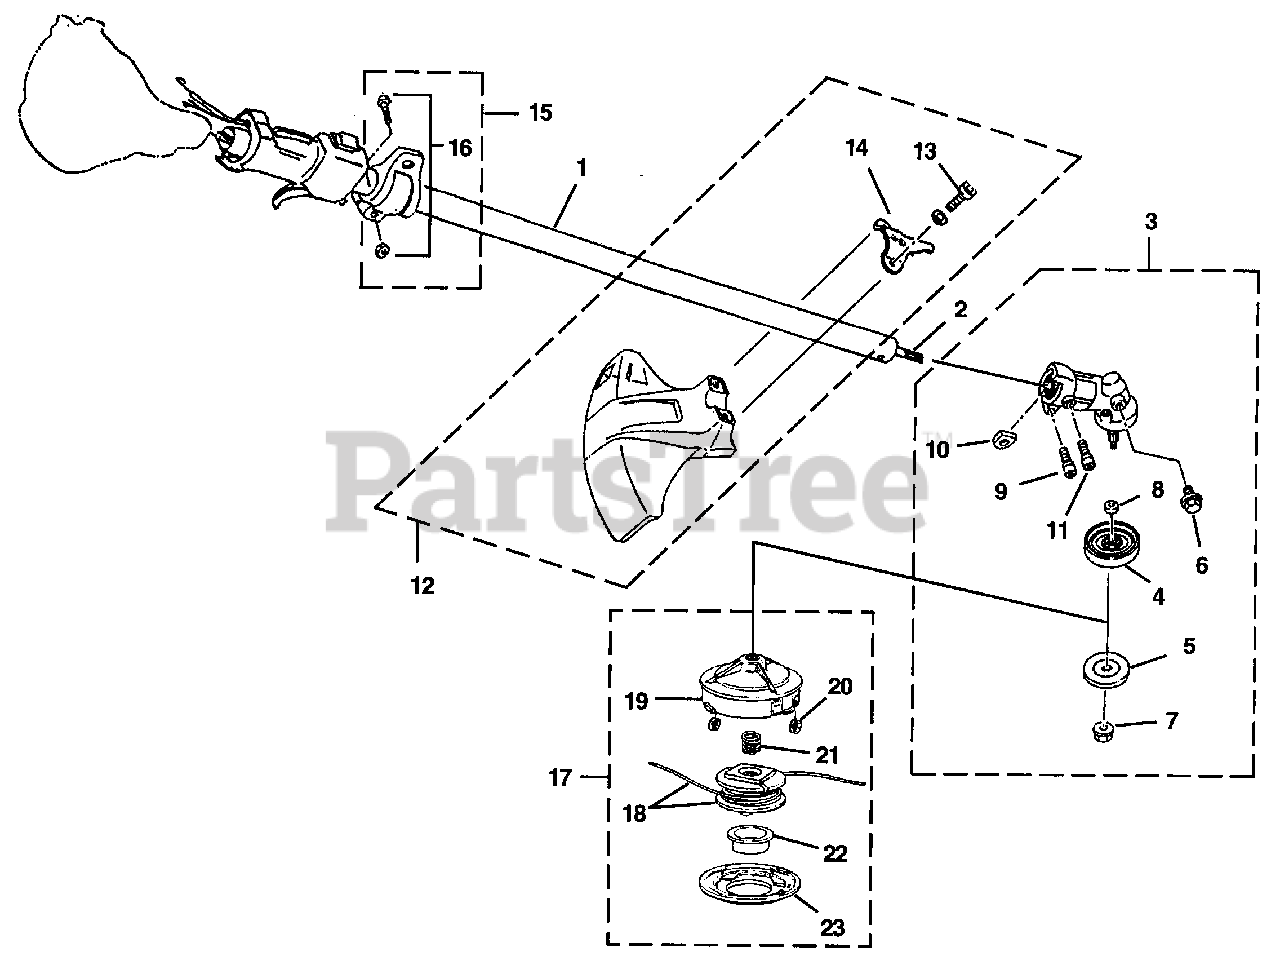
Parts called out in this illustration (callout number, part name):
1	DRIVESHAFT HOUSING
2	DRIVESHAFT
3	GEAR HEAD
4	WASHER-Flange
5	WASHER-Cupped
6	BOLT-Grease (M6 x 9)
9	BOLT ASSEMBLY (M5 x 25 SW)
11	BOLT ASSEMBLY (M5 x 12 SW)
12	DEFLECTOR ASSEMBLY
13	BOLT (M6 x 30)
15	HANGER ASSEMBLY
16	SCREW ASSEMBLY (M5 x 14)
17	STRINGHEAD ASSEMBLY (.080)
18	SPOOL & STRING (.080)
